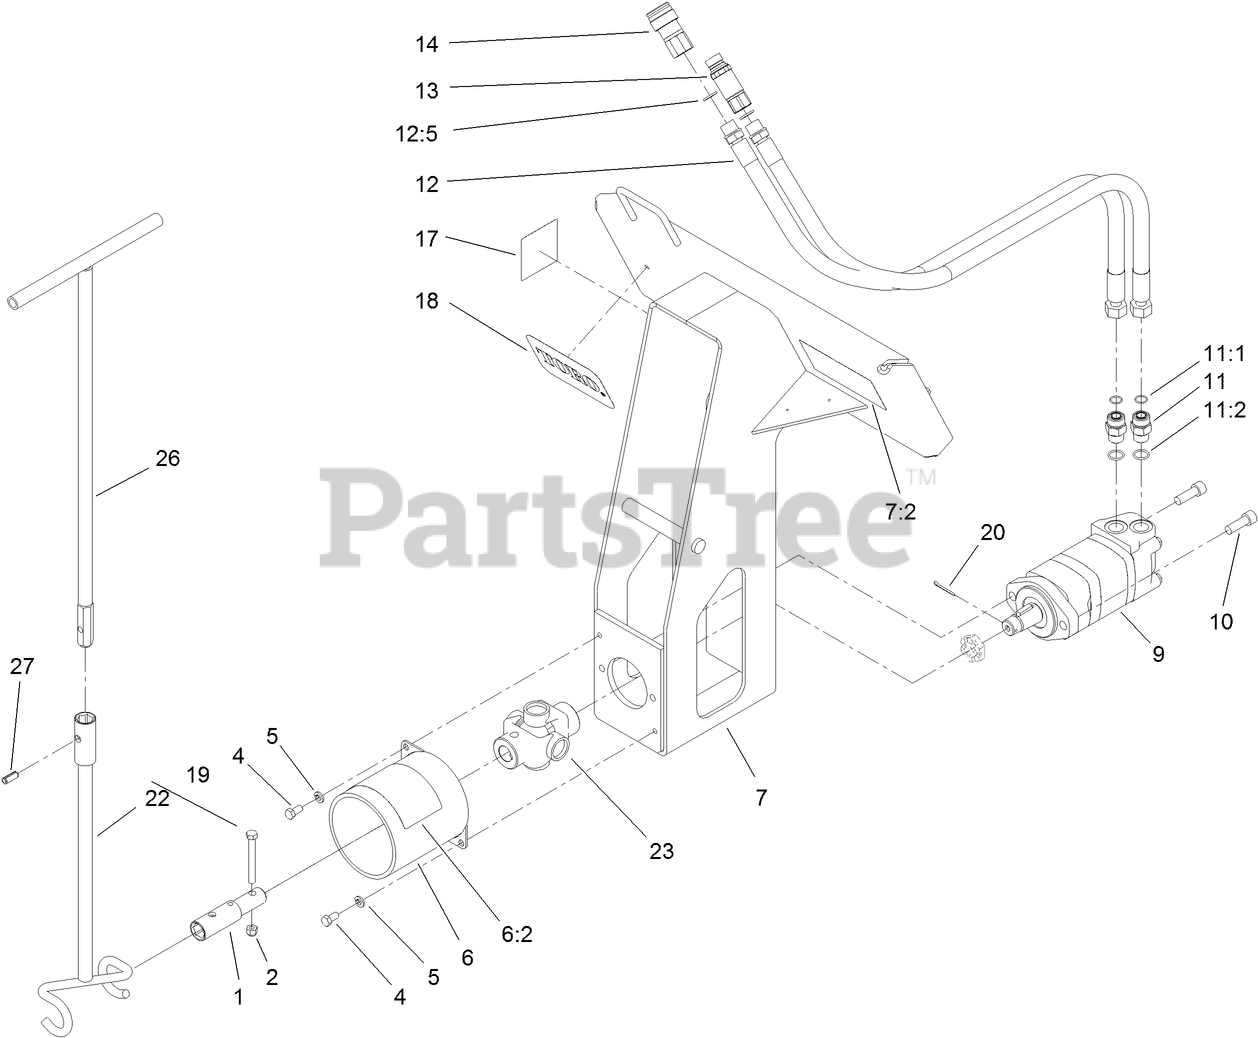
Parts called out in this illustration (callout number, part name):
1	COUPLER
2	NUT-LOCK, NI
4	SCREW-HH
5	WASHER-LOCK
6	Shield ASM
6:2	DECAL-WARNING
7	Bore Frame ASM
7:2	DECAL-WARNING
9	MOTOR-HYDRAULIC
10	SCREW-HSH
11	FITTING-STRAIGHT
11:1	O-RING
11:2	O-RING
12	HOSE ASM
12:5	O-RING
13	NIPPLE-CONNECT, PRESSURE
14	COUPLER-FACE, FLUSH
17	DECAL
18	DECAL
19	SCREW-HH
20	PIN-COTTER
22	TOOL-GUIDE, ROD
23	JOINT-UNIVERSAL
26	HANDLE-TOOL, GUIDE
27	PIN-ROLL
